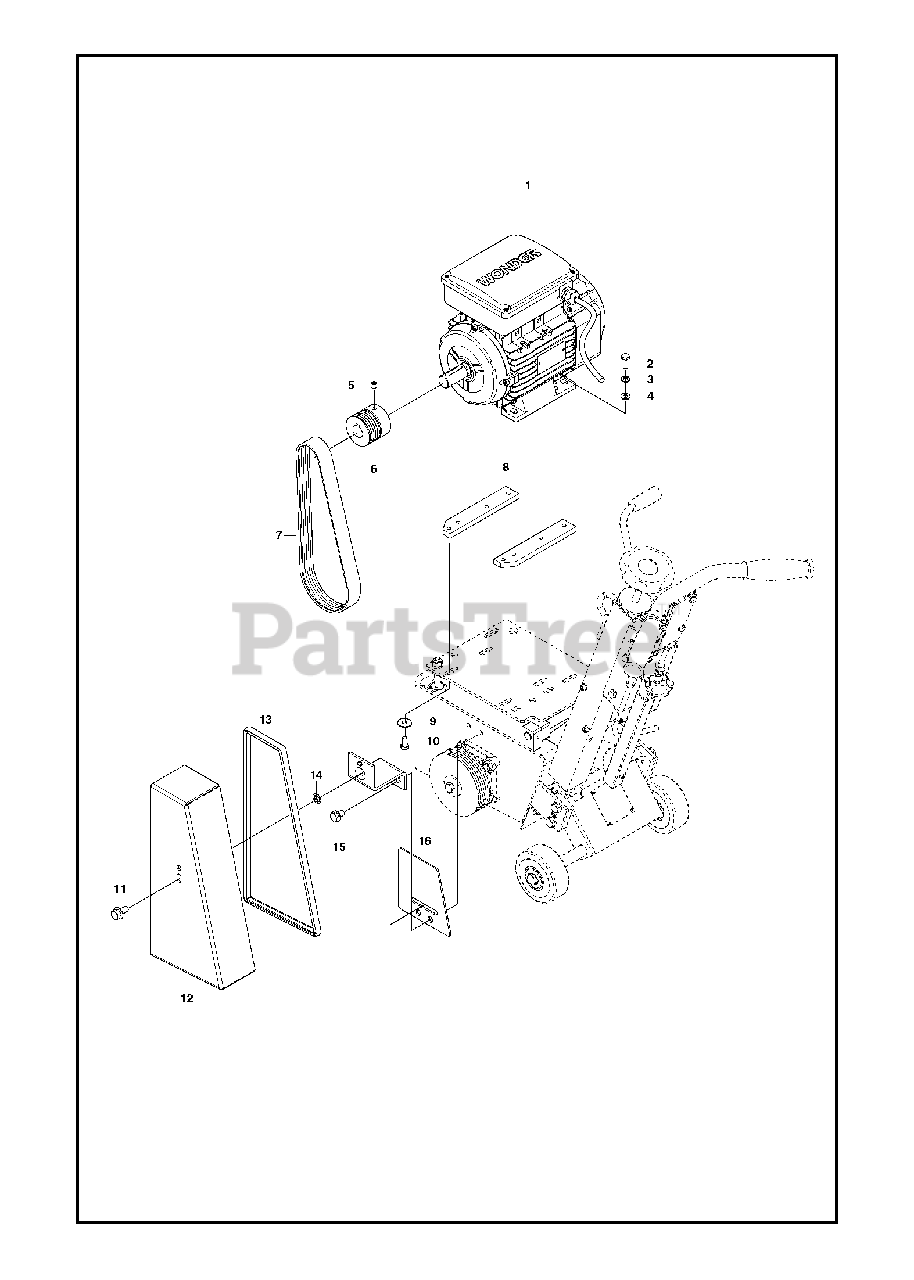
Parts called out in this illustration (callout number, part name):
3	SPRING WASHER
4	WASHER
10	SCREW EHHM
